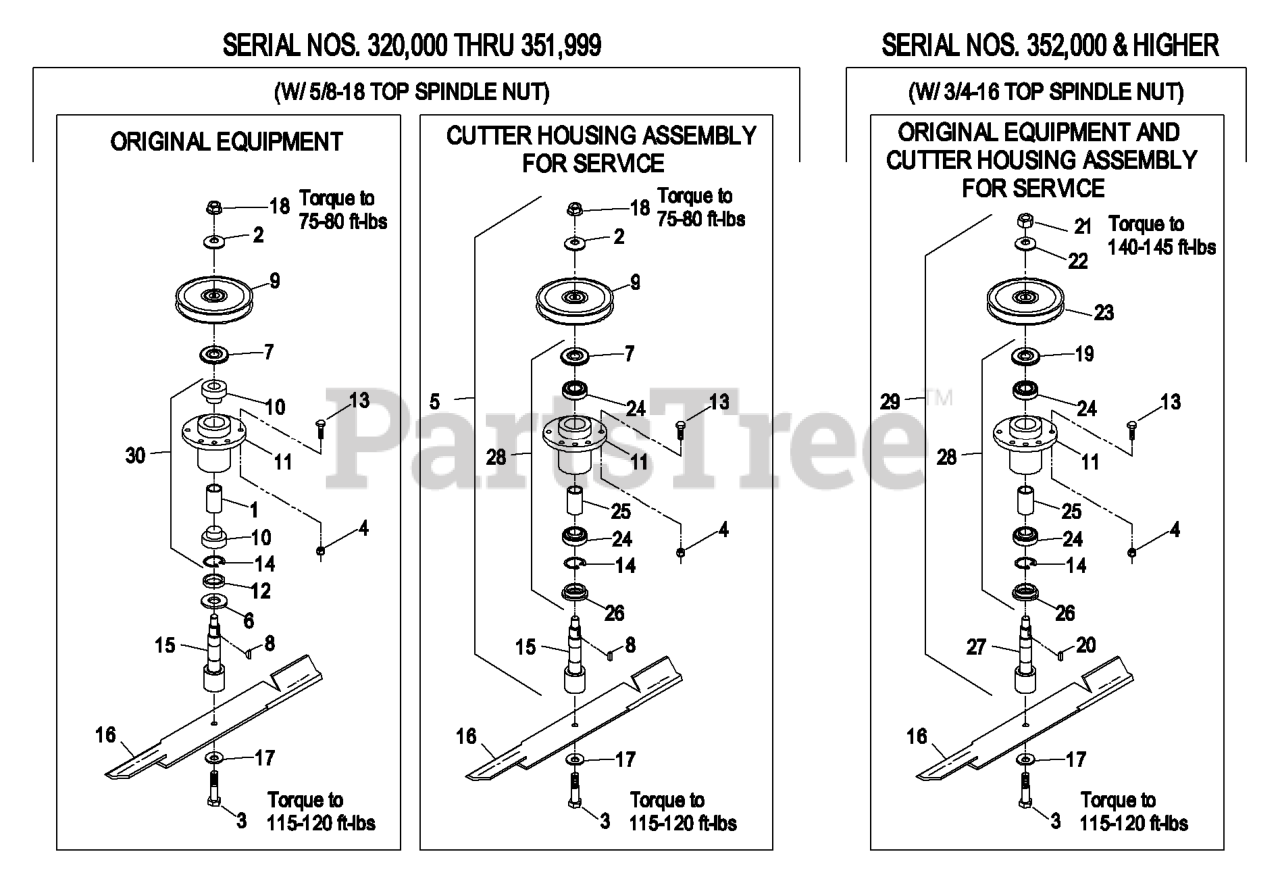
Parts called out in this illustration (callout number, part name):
1	SPACER-PULLEY/BEARING
2	WASHER-SPRING
3	SCREW-CAP
4	NUT-LOCK, NI
5	ASM,SPINDLE HSG COMPLETE
6	GUARD-BEARING, BOTTOM
7	GUARD,BEARING TOP .880
8	KEY-WOODRUFF
9	SHEAVE,BLADE DRIVE
10	BEARING
12	SPACER-BEARING
13	SCREW-HH
14	RING-SNAP
17	WASHER-BLADE BOLT, HEAVY
18	NUT FLANGE
19	GUARD-BEARING, TOP
23	SHEAVE,BLADE DRIVE 6.30
24	BEARING-JACKSHAFT
25	SPACER-BEARING
26	SPACER-GUARD, BOTTOM
27	SPINDLE,SHORT
30	Housing W/Ring,Spacer,& Brg
